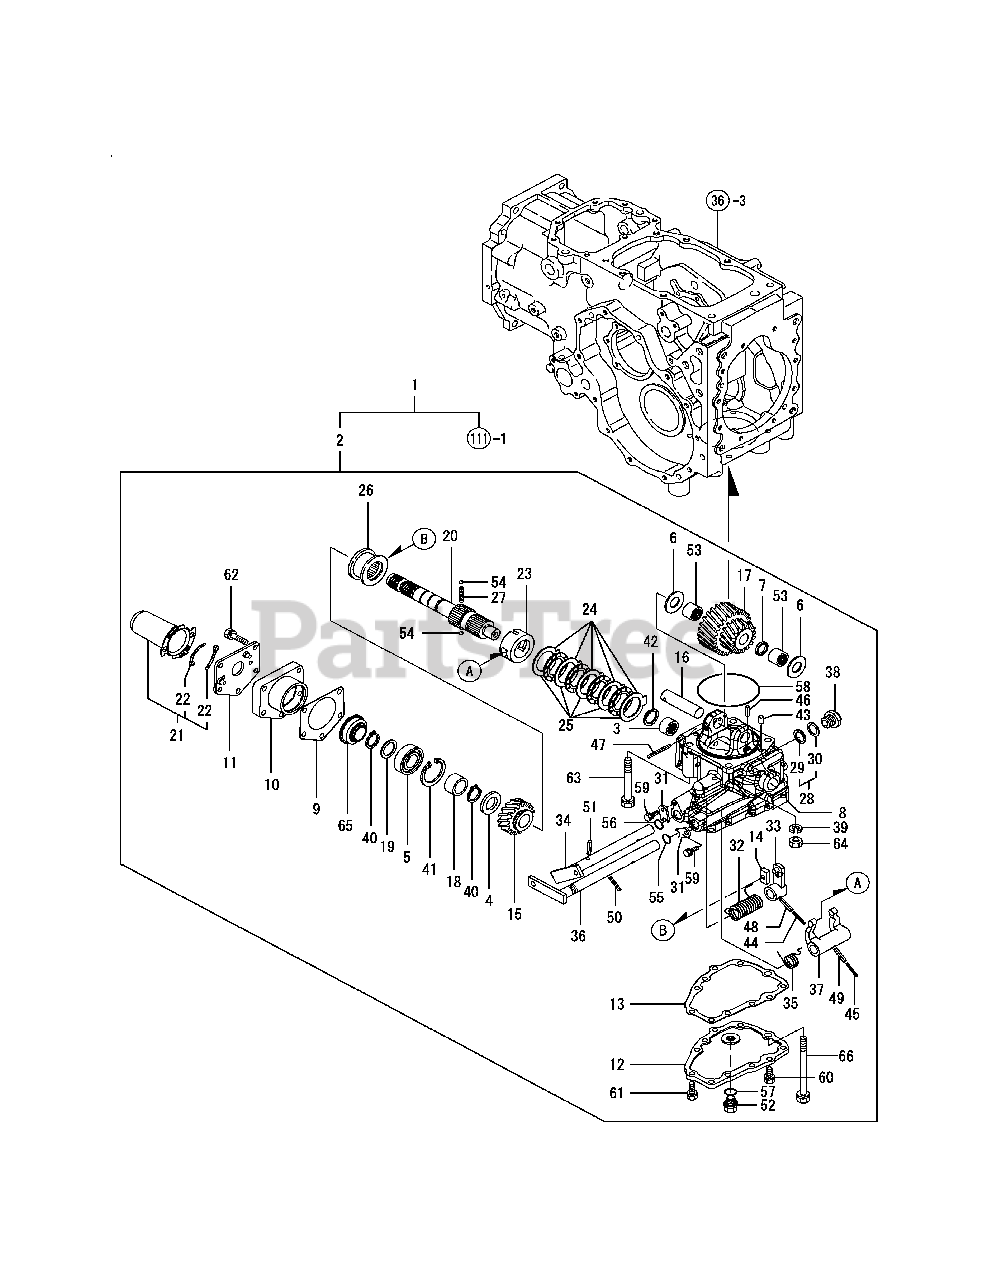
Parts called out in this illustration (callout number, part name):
1	MID PTO KIT
2	MID PTO, MISSION KIT
4	WASHER 25X42X4.8
6	WASHER 20X41X2.5
7	WASHER 20.5X25X4
8	CASE,MID PTO DRIVE
12	COVER, MID PTO CASE
13	GASKET, CASE COVER
15	GEAR, MID PTO DRIVE
18	COLLAR 25X34X19.4
19	SPACER 25X36X1.6
20	SHAFT, MID PTO DRIVE
21	COVER ASSY, SHAFT
22	SPRING, SHIFT COVER
25	SHOE. MID PTO BRAKE
26	SLIDER, MID PTO
30	GASKET 18, ROUND
33	ARM, MID PTO SHIFT
34	SHAFT, MID PTO SHIFT
36	SHAFT, MID PTO BRAKE
37	LEVER, MID PTO BRAKE
38	SWITCH, SAFETY START
39	SPRING WASHER 10
43	PARALLEL PIN 8X12
44	SPRING PIN 3.5X28
45	SPRING PIN 3.5X28
46	SPRING PIN 5X20
47	SPRING PIN 5X50
48	SPRING PIN 6X28
49	SPRING PIN 6X28
50	SPRING PIN 6X28
51	SPRING PIN 6X28
53	NEEDLE BEARING
54	BALL 1/4, STEEL
55	O-RING 1A P-12.5
56	O-RING 1A P-12.5
57	O-RING 1A P-16.0
58	O-RING 1A G-100.0
60	BOLT W/WASHER M8X16
61	BOLT W/WASHER M8X20
63	BOLT W/WASHER 10X 85
65	SEAL QLF 25471121
66	BOLT W/WASHER 10X120
